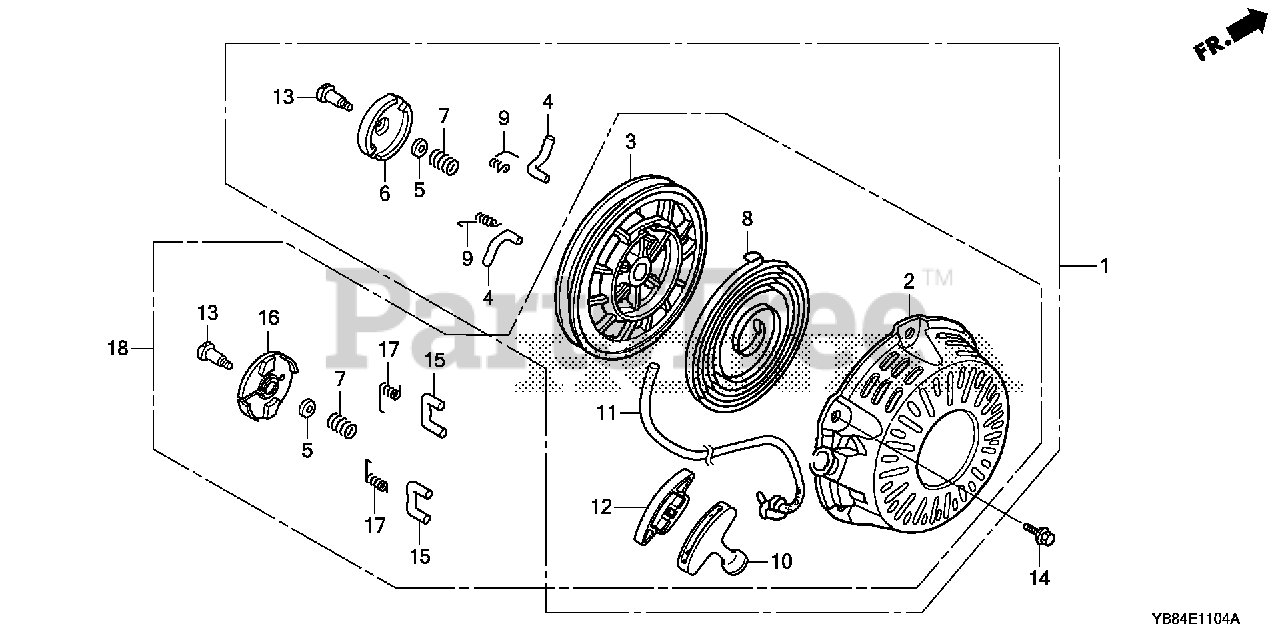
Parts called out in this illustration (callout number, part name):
2	CASE, RECOIL STARTER *R280* (POWER RED)
3	REEL, RECOIL STARTER (BLACK)
5	PLATE, FRICTION
7	SPRING, FRICTION
8	SPRING, RECOIL STARTER
10	KNOB, RECOIL STARTER
11	ROPE, RECOIL STARTER (#5X55")
12	KNOB, REINFORCEMENT
13	SCREW, SETTING
14	BOLT, FLANGE (6X8)
15	RATCHET, STARTER
16	GUIDE, RATCHET
17	SPRING, RETURN
18	STARTER ASSY., RECOIL *R280* (COO)(FOR U.S.A.) (POWER RED)
